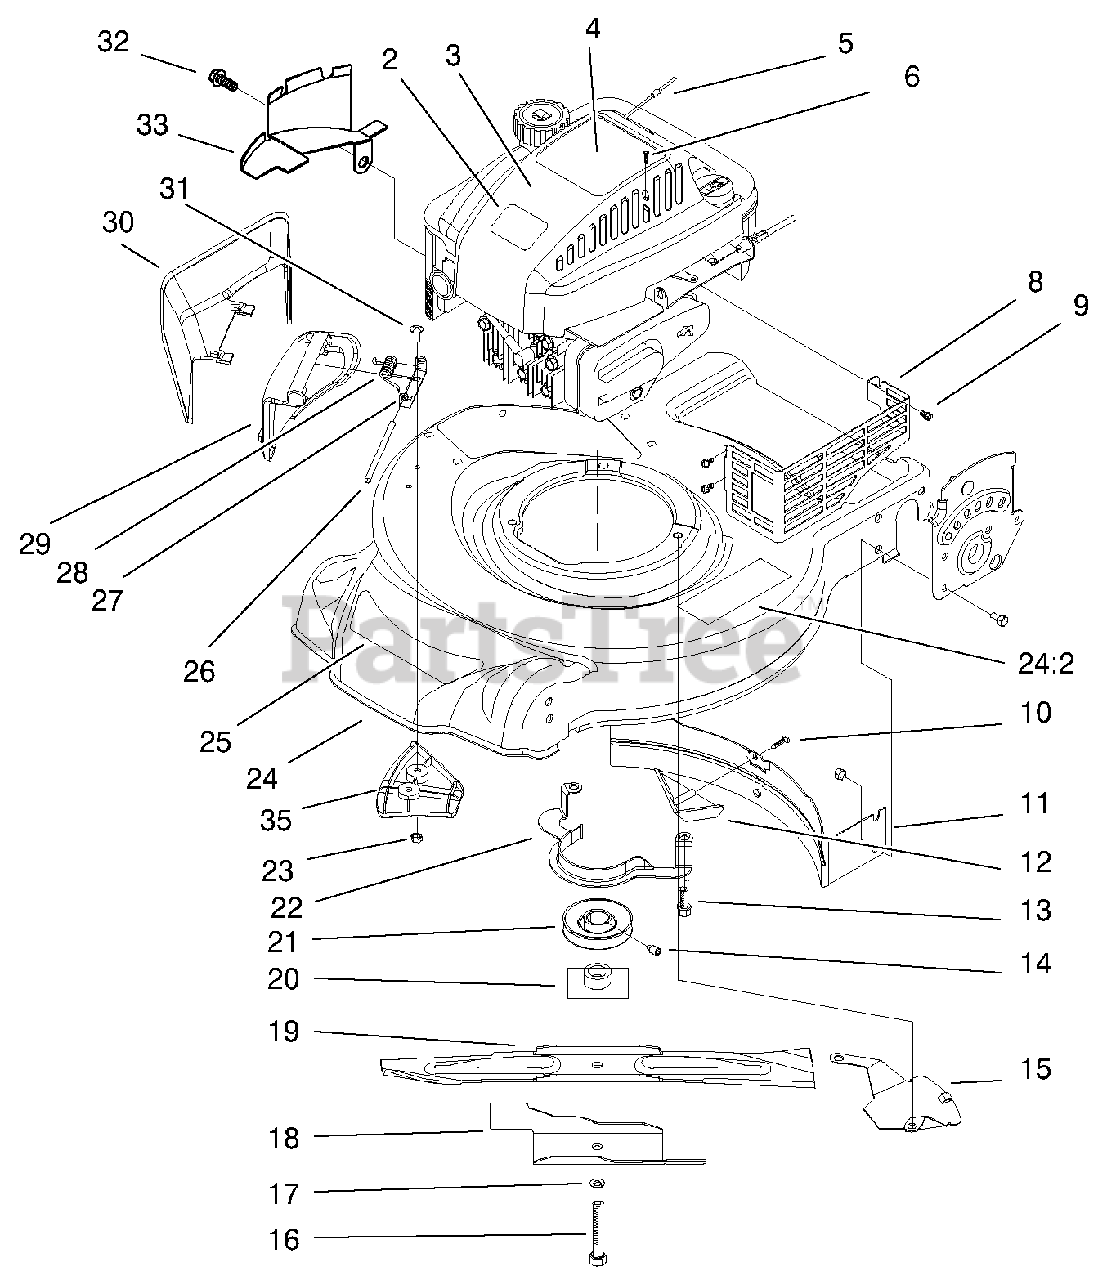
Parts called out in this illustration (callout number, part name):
1	Plate & Collar Assembly
2	Screw-Engine
3	Engine
4	Stop-Rope
5	Decal-Shroud Top
6	Screw-Recoil Cover
7	Cover- Starter
8	Shroud- Engine
9	Screw-Hex Socket Hd.
10	Decal-Warning
11	Guard-Muffler
12	Blade-21 "
13	Fan-Mulching
14	Nut-Blade
15	Decal-Oil Instruction
16	Decal-Primer
